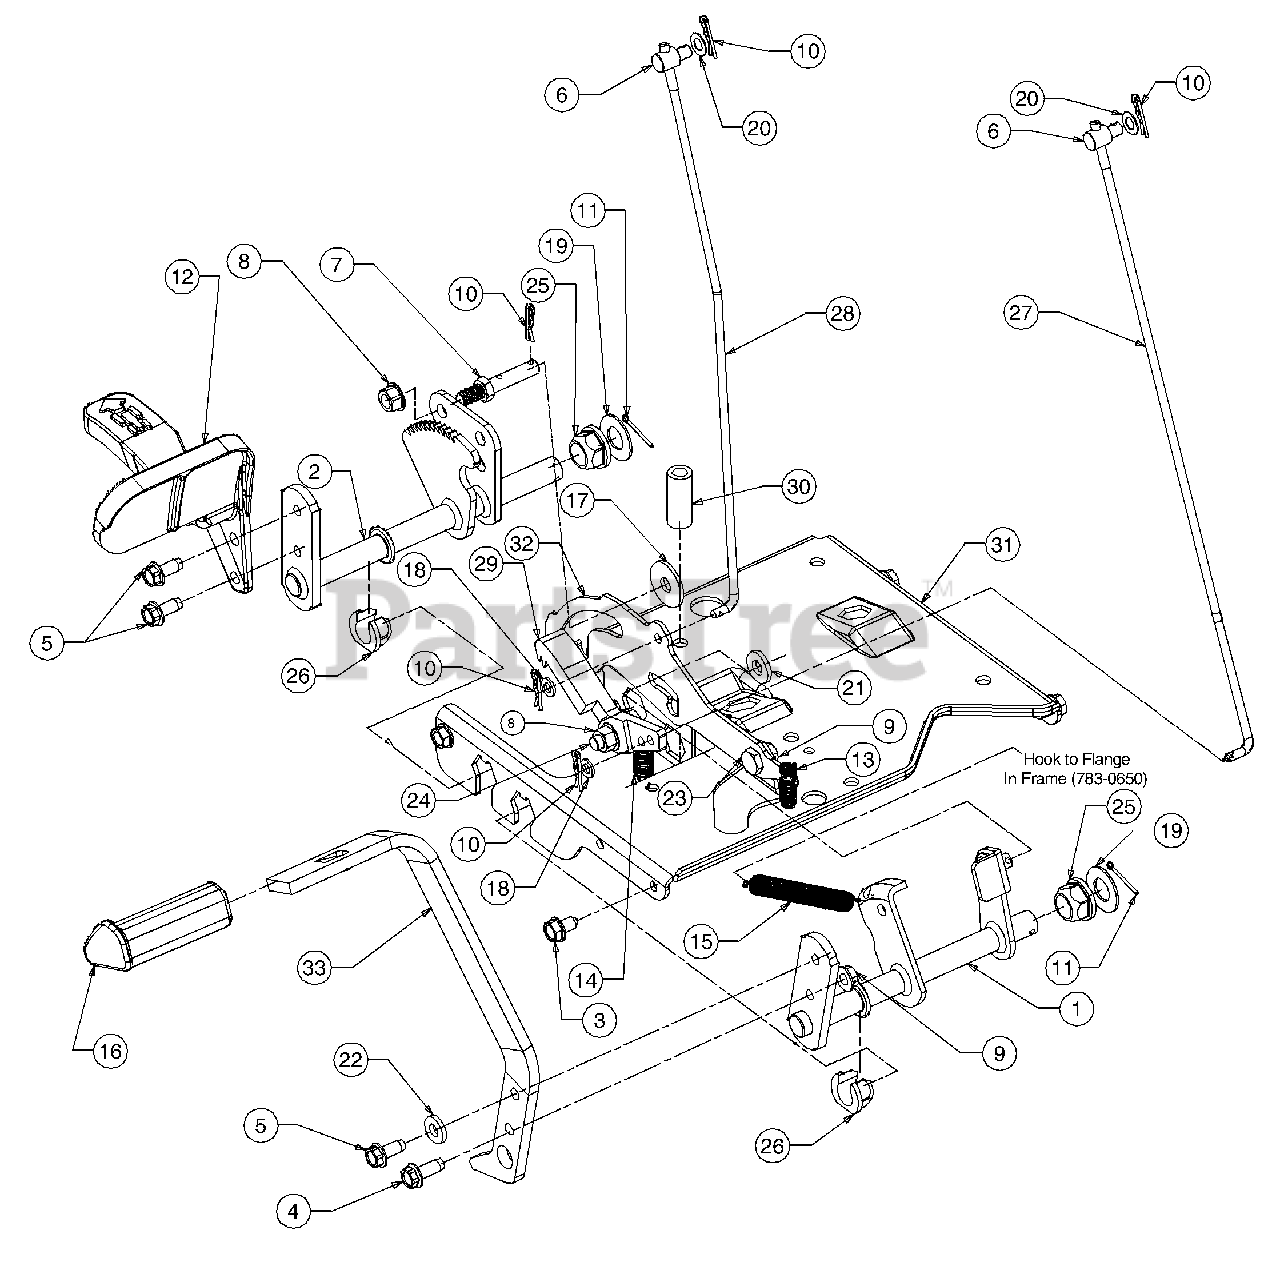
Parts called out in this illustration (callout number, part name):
1	Control Assembly, Brake
2	Control Assembly, Hydro
3	Screw, Self-tapping, 5/16-18, 0.625
4	Screw, Self-tapping, 5/16-18, 0.875
5	Screw, 5/16-18, 0.750
6	Adjustment Ferrule 1/4-20 x 1.0
7	Pin, 3/8-16, 3/8 x 2.43 Lg
8	Nut, Flange Lock, 3/8-16
9	Nut, Flange Lock, 5/16-18, Gr5
10	Pin, Cotter, .072 Dia. x 1.13 Lg
11	Pin, Cotter, 3/32, 1.0
12	Pedal, Control
13	Spring, Compression, .405 x 1.17
14	Spring, Extension, .50 OD x 1.41 Lg
15	Spring, Extension, .50 Dia x 6.37 Lg
16	Pad, Brake, Control
17	Washer, Flat, .411 x 1.25 x .100
18	Washer, Flat, .281 x .50 x .063
19	Washer, Flat .64 ID x 1.24 x .06
20	Washer, Flat, .344 ID x .62 OD
21	Washer, Flat, .406 ID x .875 OD x .105
22	Washer, Flat, .344 x .750 x .120
23	Shoulder, Screw .437 x 1.62 Lg
24	Screw, Shoulder, .500 Dia x .434
25	Bearing, Hex Flange
26	Bearing, Hex Flange, .628 ID, Split
27	Rod, Control, Cruise
28	Rod, Control, Brake Lock
29	Latch, Cruise
30	Spacer, .385 ID x .635 OD x 1.54
32	Bracket, Lockout, Hydro
